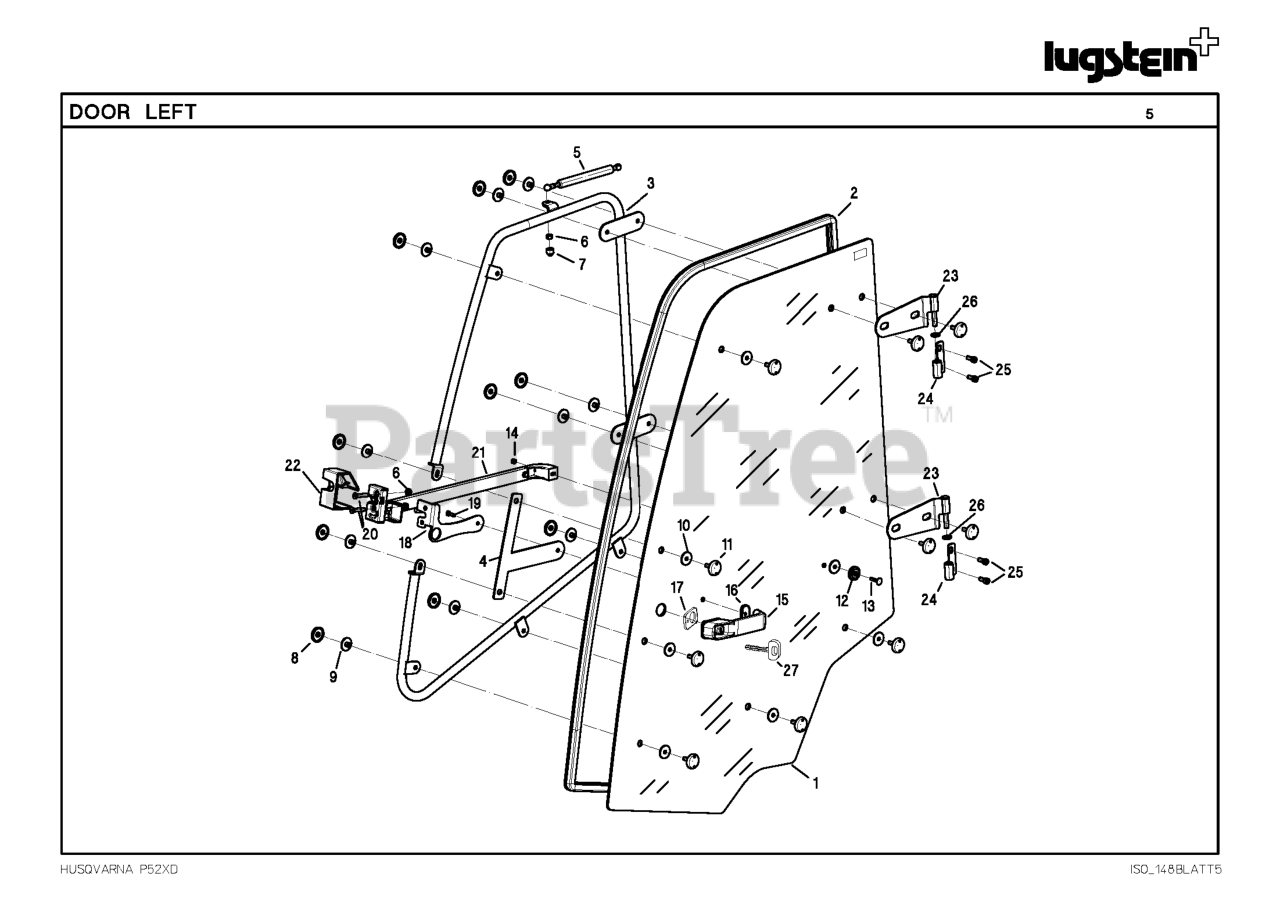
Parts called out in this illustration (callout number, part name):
6	LOCKNUT M8
7	PROTECTIVE COVER
14	LOCKNUT M6
